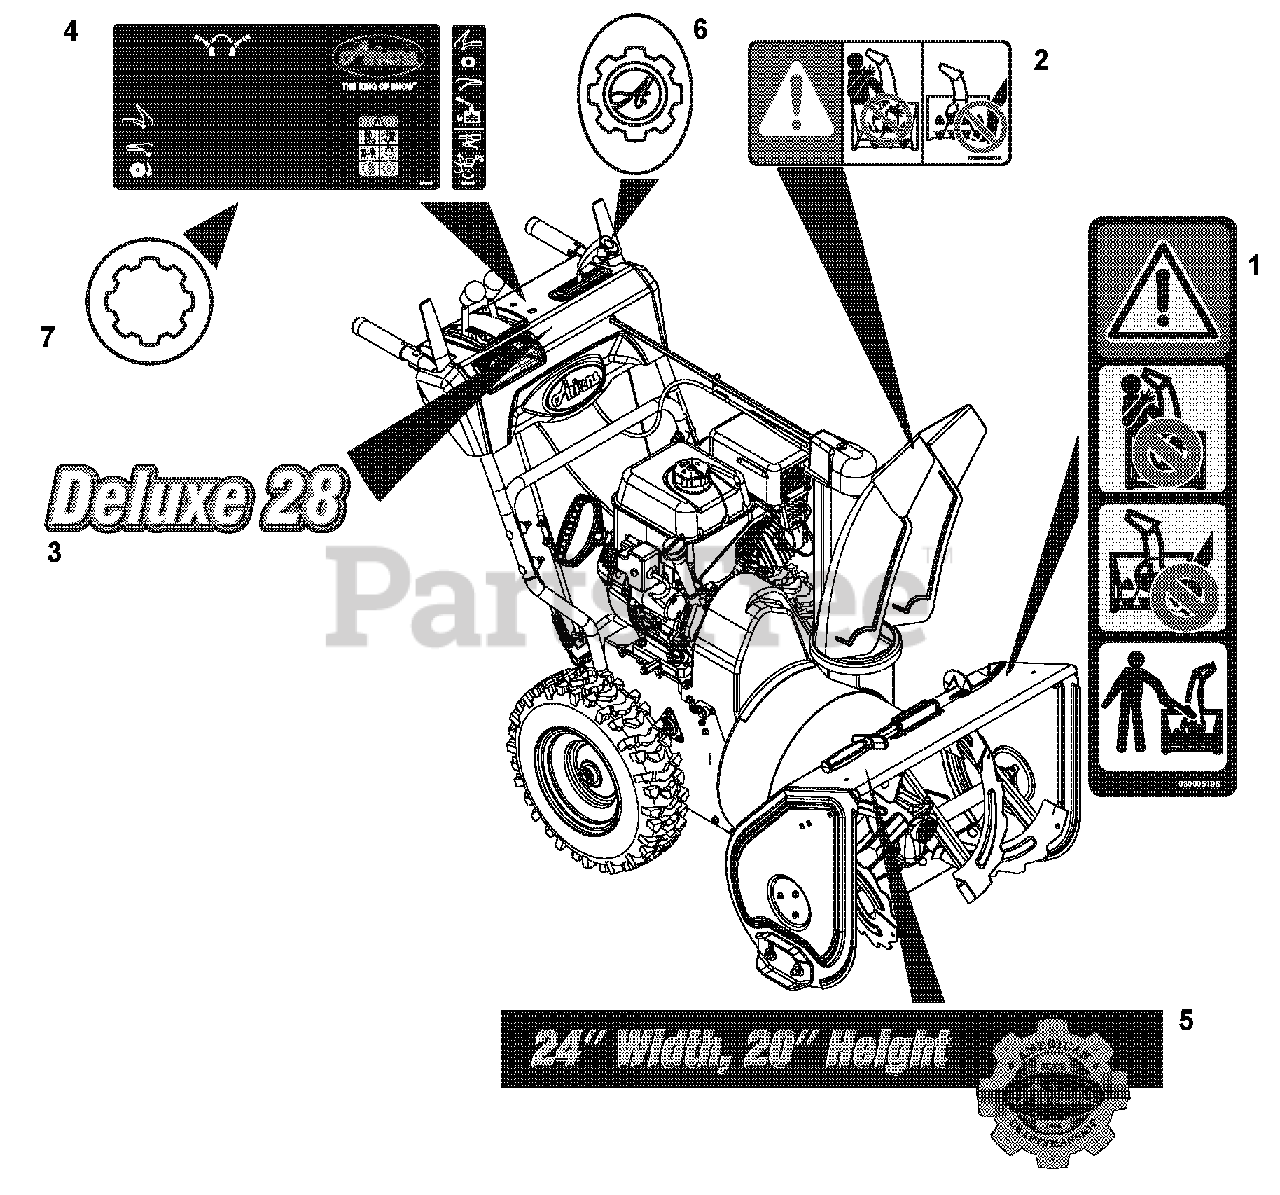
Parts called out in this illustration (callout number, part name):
1	DECAL, DANGER - ROTATING PARTS
2	DECAL, DANGER
3	DECAL, DELUXE 28 SM DASH
4	DECAL, CONTROL - DELUXE TRACK
6	DECAL, ARIENS GEAR - RAISED
7	DECAL,AUTODIFFERENTIAL
